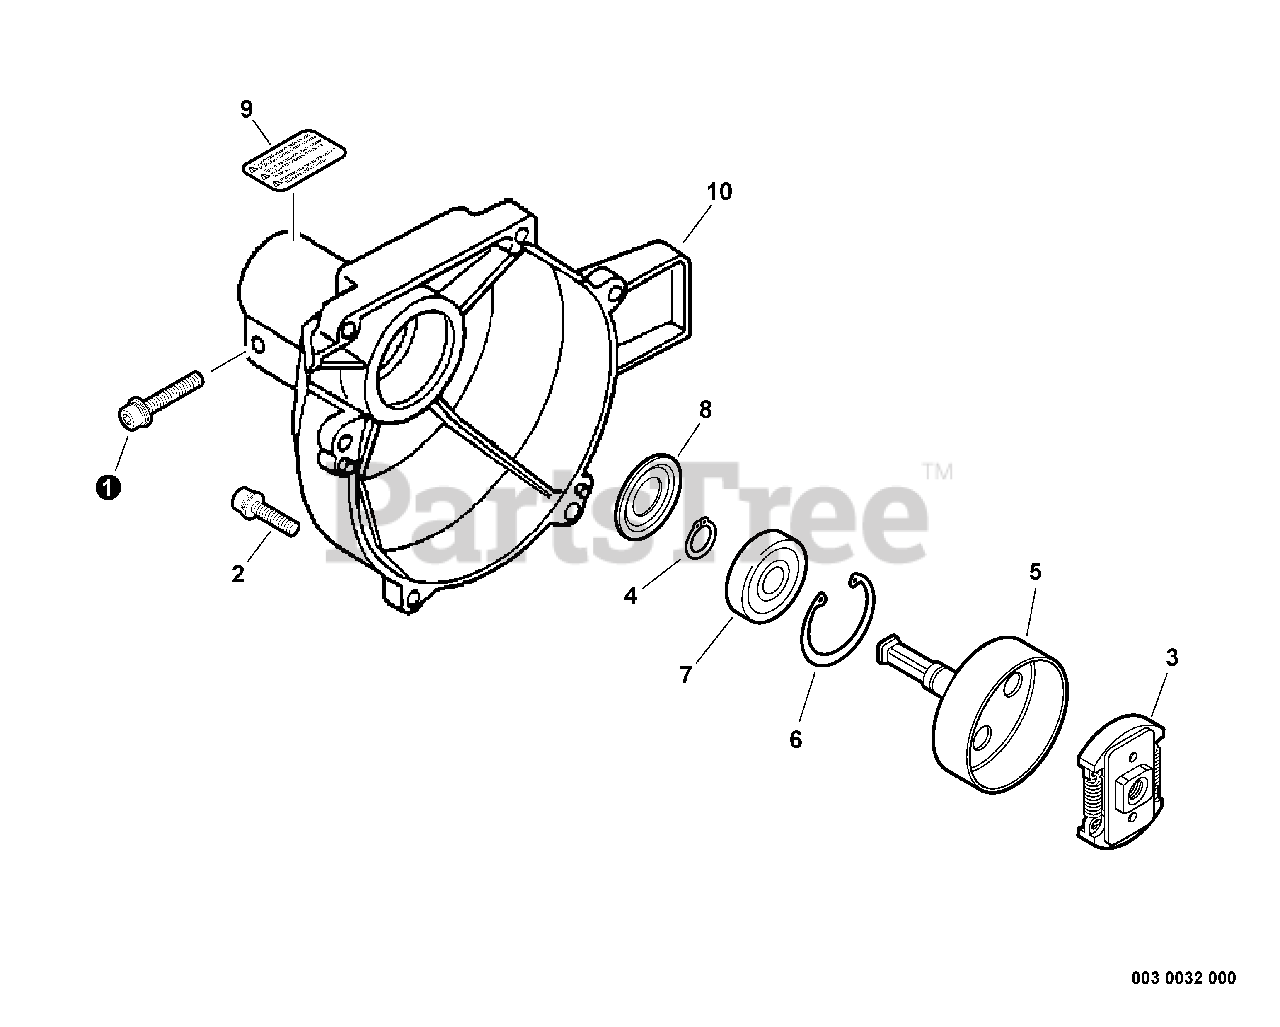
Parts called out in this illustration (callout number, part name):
1	SCREW - 5X25
2	SCREW - 4X16
3	CLUTCH ASSY
4	RING, RETAINING - 12
5	DRUM, CLUTCH
6	RING, RETAINING - 32
7	BEARING, BALL - 6201
8	RETAINER, PIPE
9	LABEL - CAUTION
10	CASE, FAN - ORANGE
